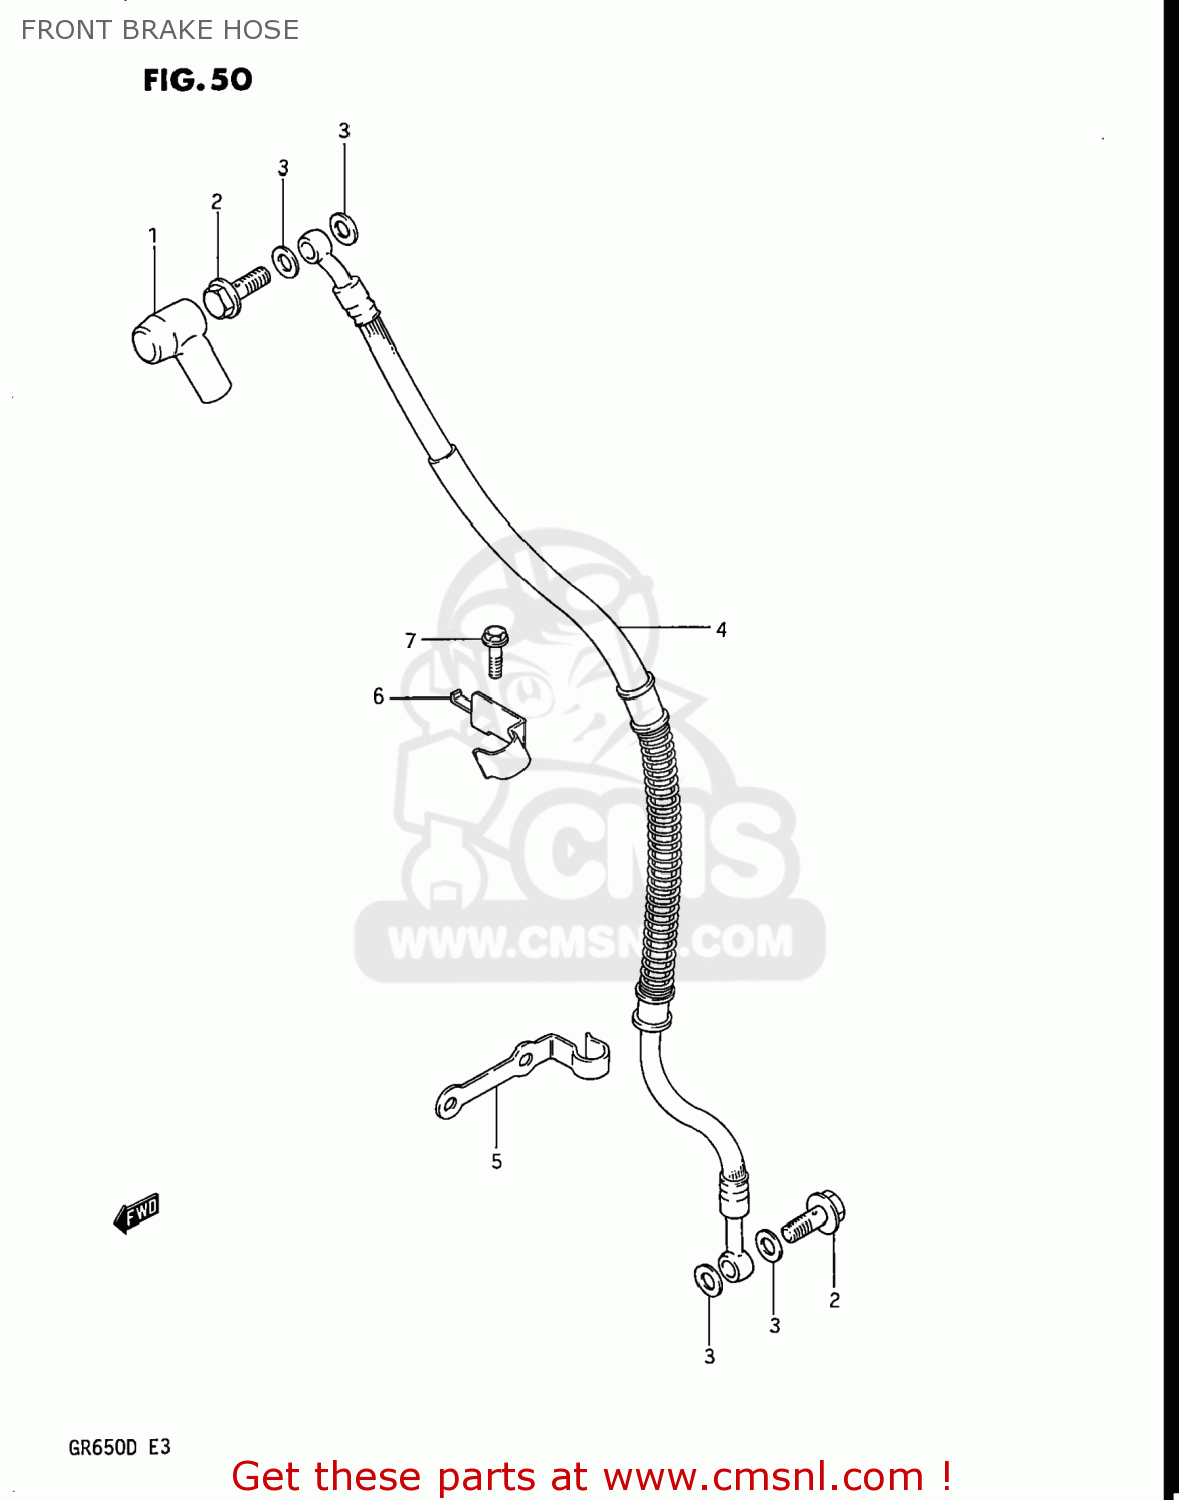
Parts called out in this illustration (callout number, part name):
1	BOOT,MASTER CYLINDER
2	BOLT UNION
3	WASHER
4	HOSE,FRONT BRAKE
5	GUIDE,BRAKE HOSE NO.2
6	GUIDE
7	BOLT
